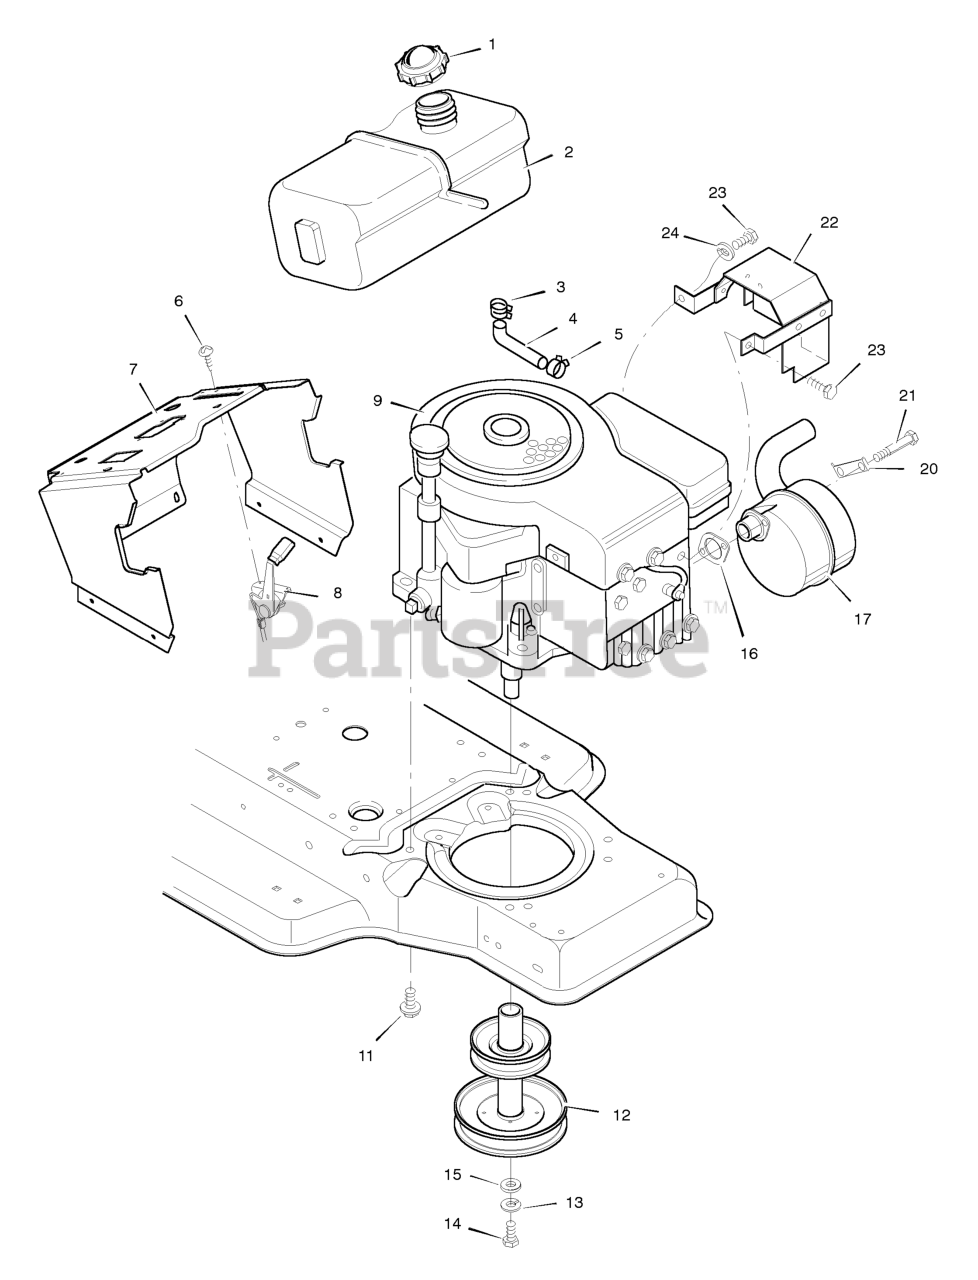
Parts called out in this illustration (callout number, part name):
1	Fuel Cap
2	Fuel Tank
3	Hose Clamp
4	Fuel Line
5	Hose Clamp
7	Support, Dash
8	Throttle Control
9	Engine *
11	Bolt, Engine Mount
12	Stack Pulley Assembly
13	Lockwasher
14	Bolt, Hex
16	GASKET, Exhaust
17	Muffler
20	Lock, Screw
22	Shield, Heat
